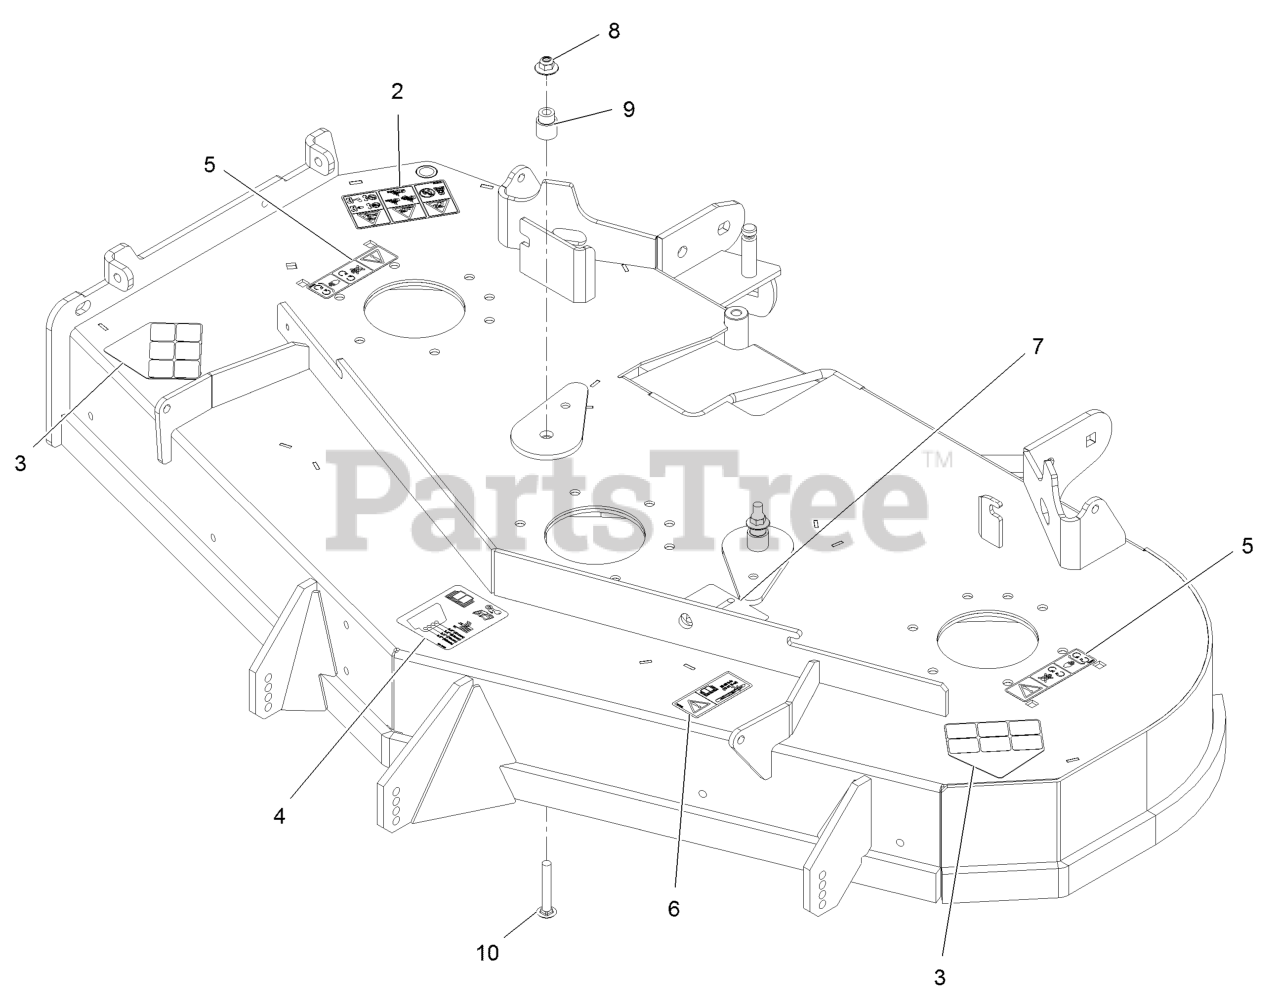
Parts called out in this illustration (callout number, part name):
2	DECAL-DANGER
3	DECAL-DANGER
4	DECAL-ROLLER, ANTI-SCALP
5	DECAL-COVER, MISSING
6	DECAL-BOLT TORQUE
7	DECAL-BELT ROUTING
8	Nut-Nyloc 3/8-16 Flg
9	BUSHING-IDLER
10	SCREW-CARR
